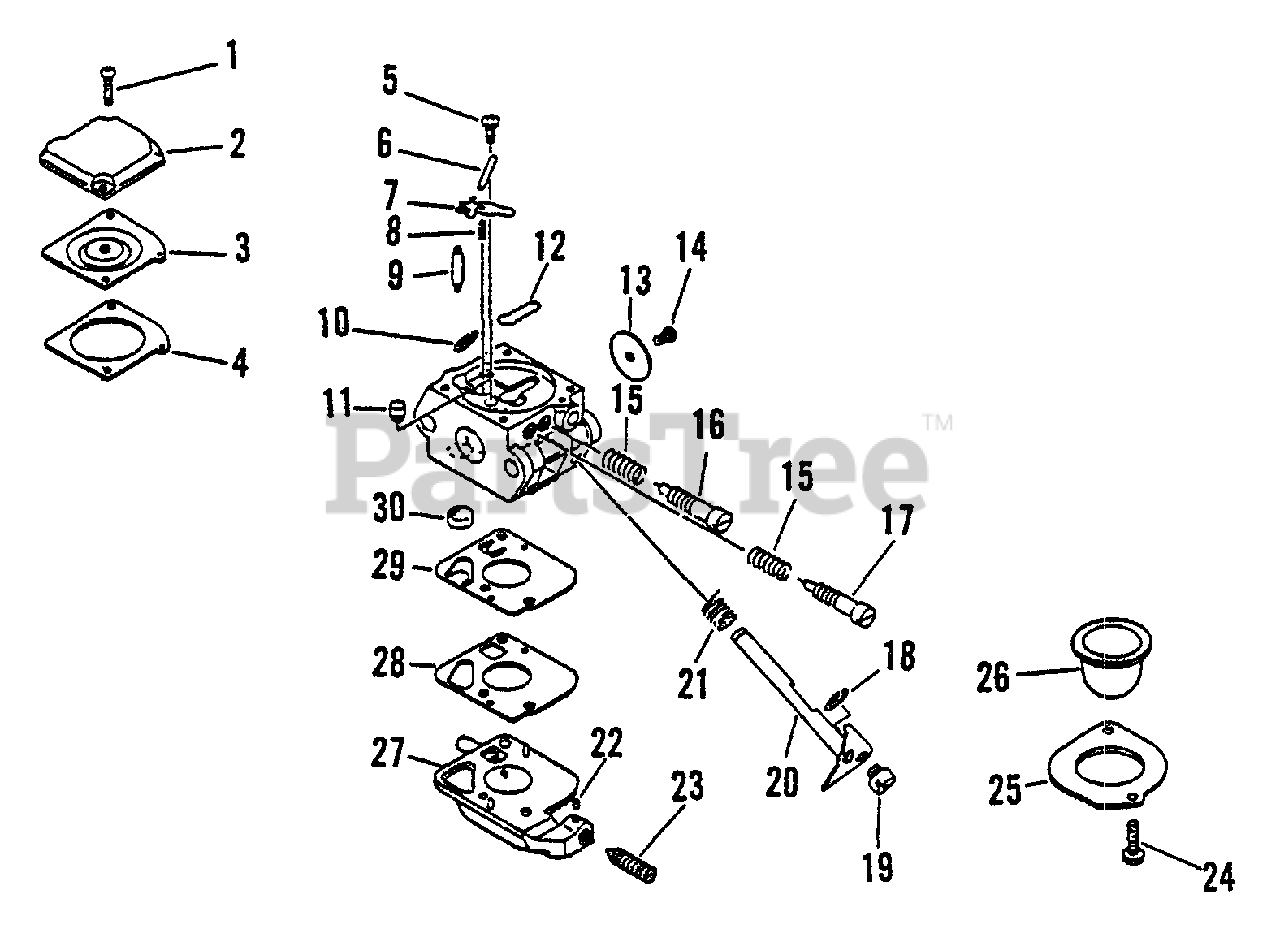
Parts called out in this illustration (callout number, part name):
2	COVER, METERING
3	DIAPHRAGM
4	GASKET, METERING
5	SCREW
6	PIN
7	LEVER, METERING
8	SPRING
9	VALVE, NEEDLE
10	RING, RETAINING
11	NOZZLE, CHECK VALVE
12	PLUG, WELCH
13	VALVE, THROTTLE
16	NEEDLE - HIGH SPEED
17	NEEDLE - MIXTURE
18	CLIP
19	SWIVEL
20	SHAFT, THROTTLE
21	SPRING, RETURN
22	PIECE, FRICTION
23	SCREW, IDLE ADJUST
24	SCREW, RETAINER
25	RETAINER, PURGE BULB
26	BULB, PURGE
27	BASE, PURGE
28	GASKET, PURGE
29	DIAPHRAGM, PURGE
30	STRAINER
